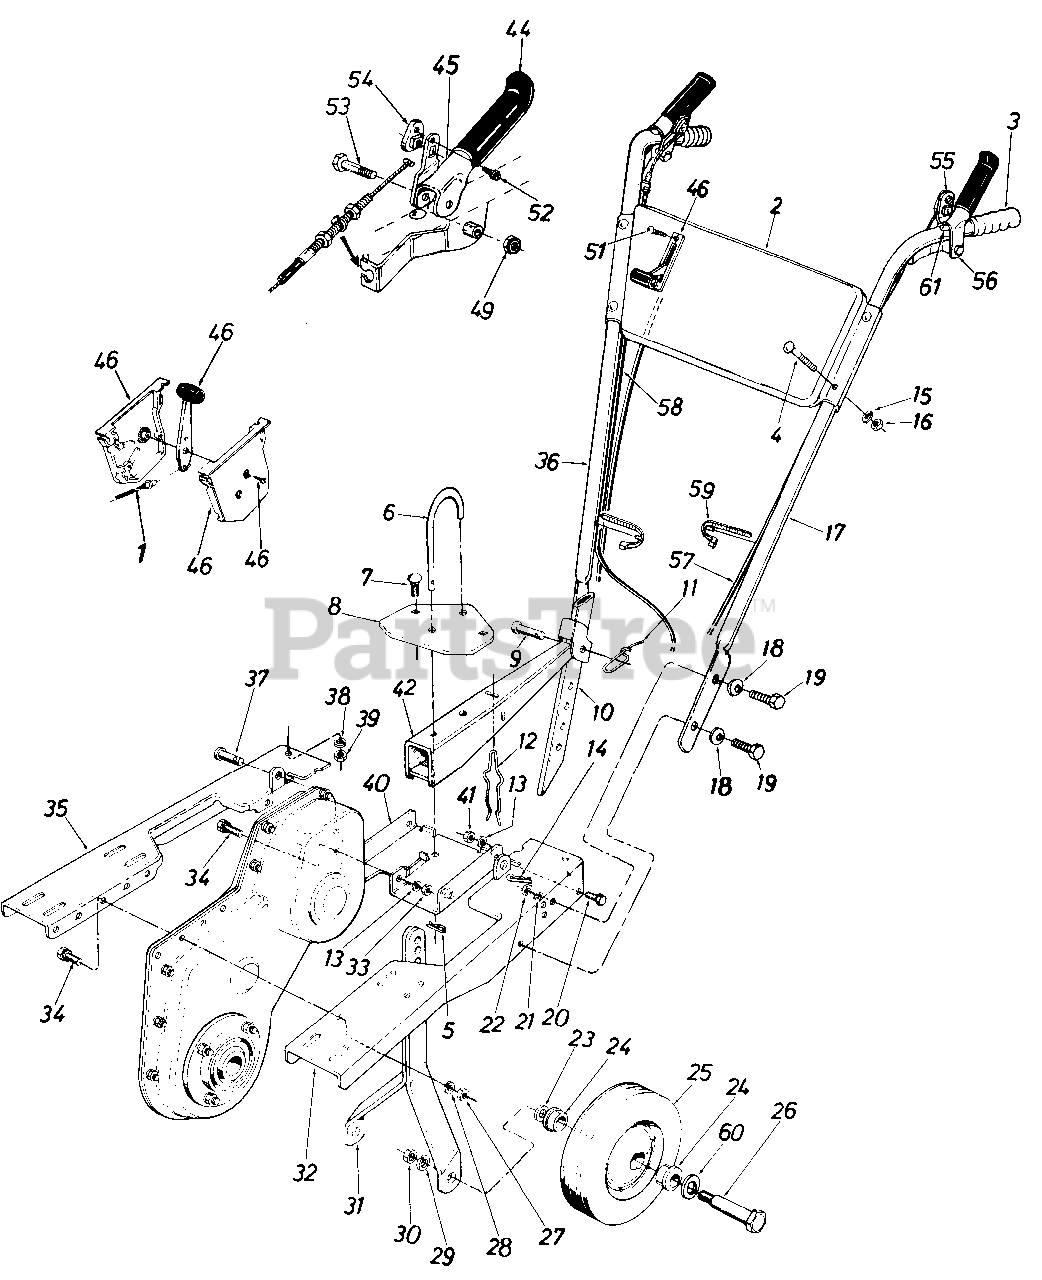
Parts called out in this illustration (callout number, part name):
1	Throttle Control Wire-35"
2	Handle Panel Ass'y.
3	Handle Grip
4	Carriage Bolt 5/16-18 x 1.75"
5	Internal Cotter Pin
6	"U"-Clevis Pin .500" Dia.
7	Carriage Bolt 5/16-18 x .75"
8	"U"-Channel Plate
9	Clevis Pin .375" Dia.
10	Depth Bar
11	Spring Pin
12	Depth Bar Spring
13	L-Wash. 5/16" I.D.
14	Internal Cotter Pin
15	L-Wash. 5/16" I.D.
16	Hex Nut 5/16-18 Thd.
17	Handle-L.H.
18	Belleville Wash. 3/8" I.D.
19	Hex Bolt 3/8-16 x 1.00" Lg.
20	Hex Bolt 5/16-18 x .75" Lg.
21	L-Wash. 3/8" I.D.
22	Hex Nut 3/8-16 Thd.
23	Belleville Wash. .505 I.D. x 1.00" O.D.
24	Fl. Bearing w/Flats .631 I.D.
25	Wheel Ass'y. Comp. 10 x 1.75
26	Shoulder Bolt .625" Dia. x 2.75" Lg.
27	Hex Nut 5/16-18 Thd.
28	L-Wash. 5/16" I.D.
29	L-Wash. 1/2" I.D.
30	Hex Ins. L-Nut 1/2-20 Thd.
31	Wheel Bracket Ass'y.
32	Engine"U"-Channel Ass'y.-L. H .
33	Hex Nut 5/16-18 Thd.
34	Hex Sems Bolt 5/16-18 x 1.00" Lg.
35	Engine"U"-Channel Ass'y.-R.H.
36	Handle-R.H.
37	Clevis Pin .375" Dia.
38	L-Wash. 5/16" I.D.
39	Hex Nut 5/16-18 Thd.
40	"U"-Channel Bracket Ass'y.
41	Hex Nut 5/16-18 Thd.
42	Tailpiece Ass'y.
44	Clutch Vinyl Grip
45	Clutch Grip Ass'y.-R.H.
46	Throttle Control Box Ass'y.
49	Hex Ins. L-Nut 3/8-24 Thd.
51	Self-Tap Scr. #10 x 1/2" Lg.
52	Self-Tap Scr. #10 x .44" Lg.
53	Hex Bolt 3/8-24 x 2.0" Lg.
54	Barrel Cable Hold-Down-R.H.
55	Barrel Cable Hold-Down-L.H.
56	Clutch Grip Ass'y.-L.H.
57	Control Cable
58	Control Cable
59	Cable Tie
60	Fl-Wash. .640 I.D. x 1.24"
61	Plug
